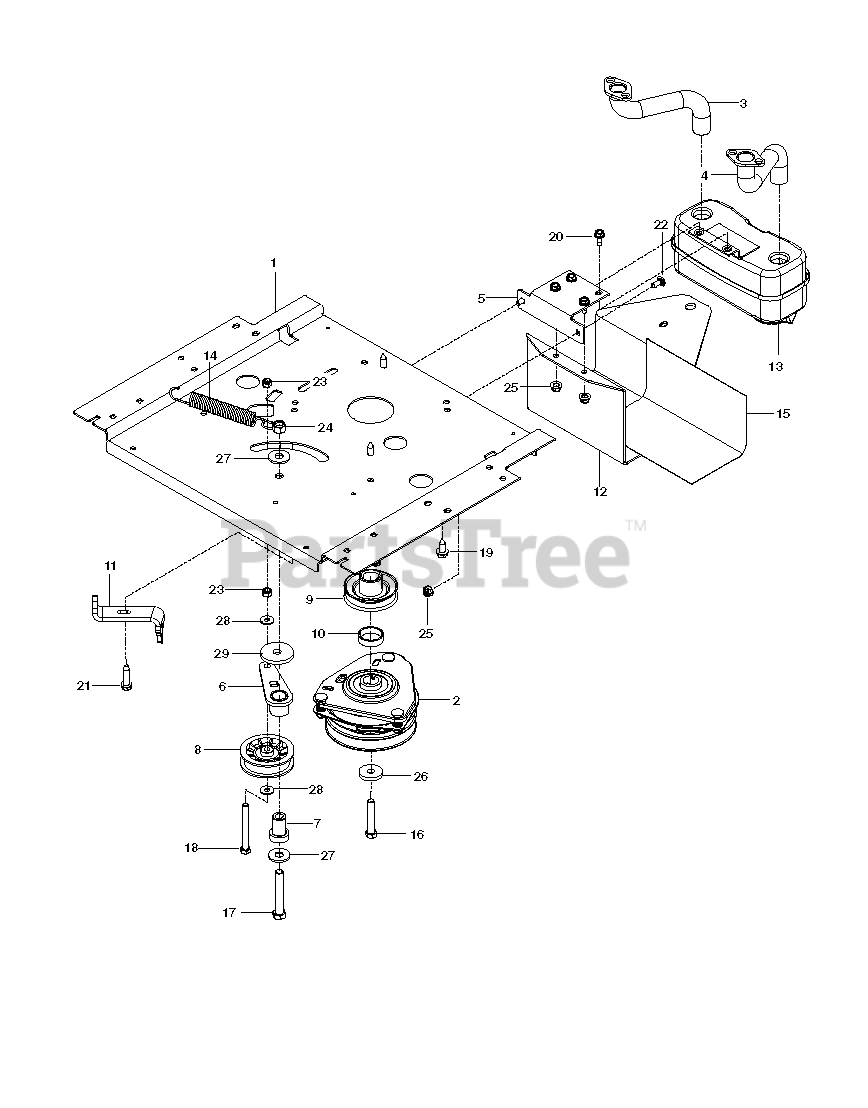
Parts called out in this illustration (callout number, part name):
3	TUBE MANIFOLD LH
4	EXHAUST TUBE RH
5	BRACKET, MUFFLER, BLACK
6	IDLER ARM
7	IDLER SPINDLE
8	PULLEY, IDLER
9	PULLEY, ENGINE
10	SPACER, HUB PULLEY
12	GUARD, MUFFLER, BLACK
13	MUFFLER ASM TWIN
14	SPRING, DECK DRIVE
15	HEAT SHIELD
16	HCS 7/16-20 X 2.5 GR8
17	HCS 1/2C X 3 1/4
18	HCS 3/8-16X3 1/2 GR5
19	HHFS 3/8-16 X 1.0 THD FORMING
20	BOLT 5/16-18 X 3/4
21	BOLT 3/8-16 X 1 1/2 ZINC CLEAR
22	BOLT 5/16C X 3/4" CARRIAGE
23	NUT 3/8-16 NYLOC
24	NUT 1/2-13 HEX NYLOC ZD
25	5/16-18 NYLOC FLANGE NUT
27	WASH USS FLAT 1/2
28	WASHER 5/16 FLAT
29	HEAVY WASHER
